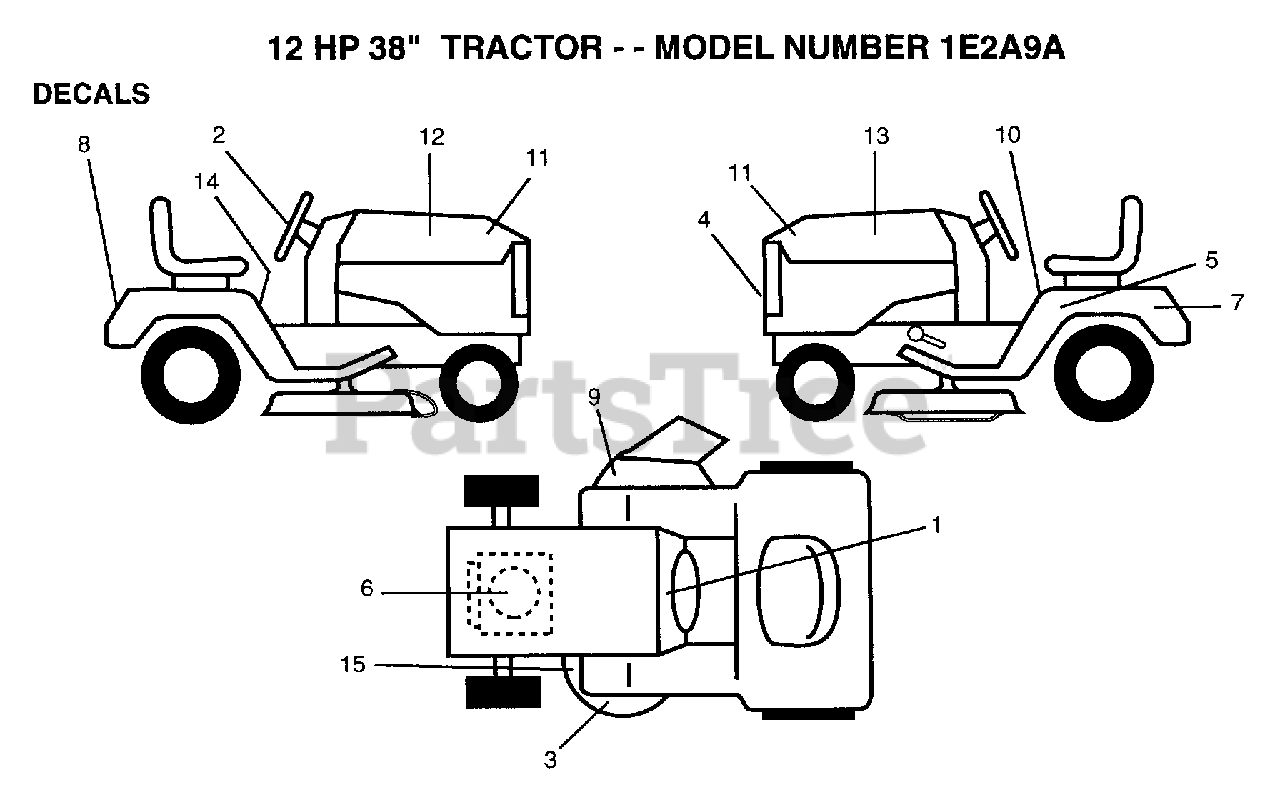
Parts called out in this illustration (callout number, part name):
2	"DECAL,STR WHL"
4	GRILL DECAL
5	IND HGT DECK DECA
6	DECAL.ENG.271967
7	DECAL
8	FENDER DECAL
9	"DECAL, WARNING"
10	DECAL CAUTION
11	"DECAL,HOOD"
12	"DECAL,STP HD RH"
13	"DECAL,STP HD LH"
14	DECAL.FEND.QUICKS
15	DECAL, V-BELT 38"
